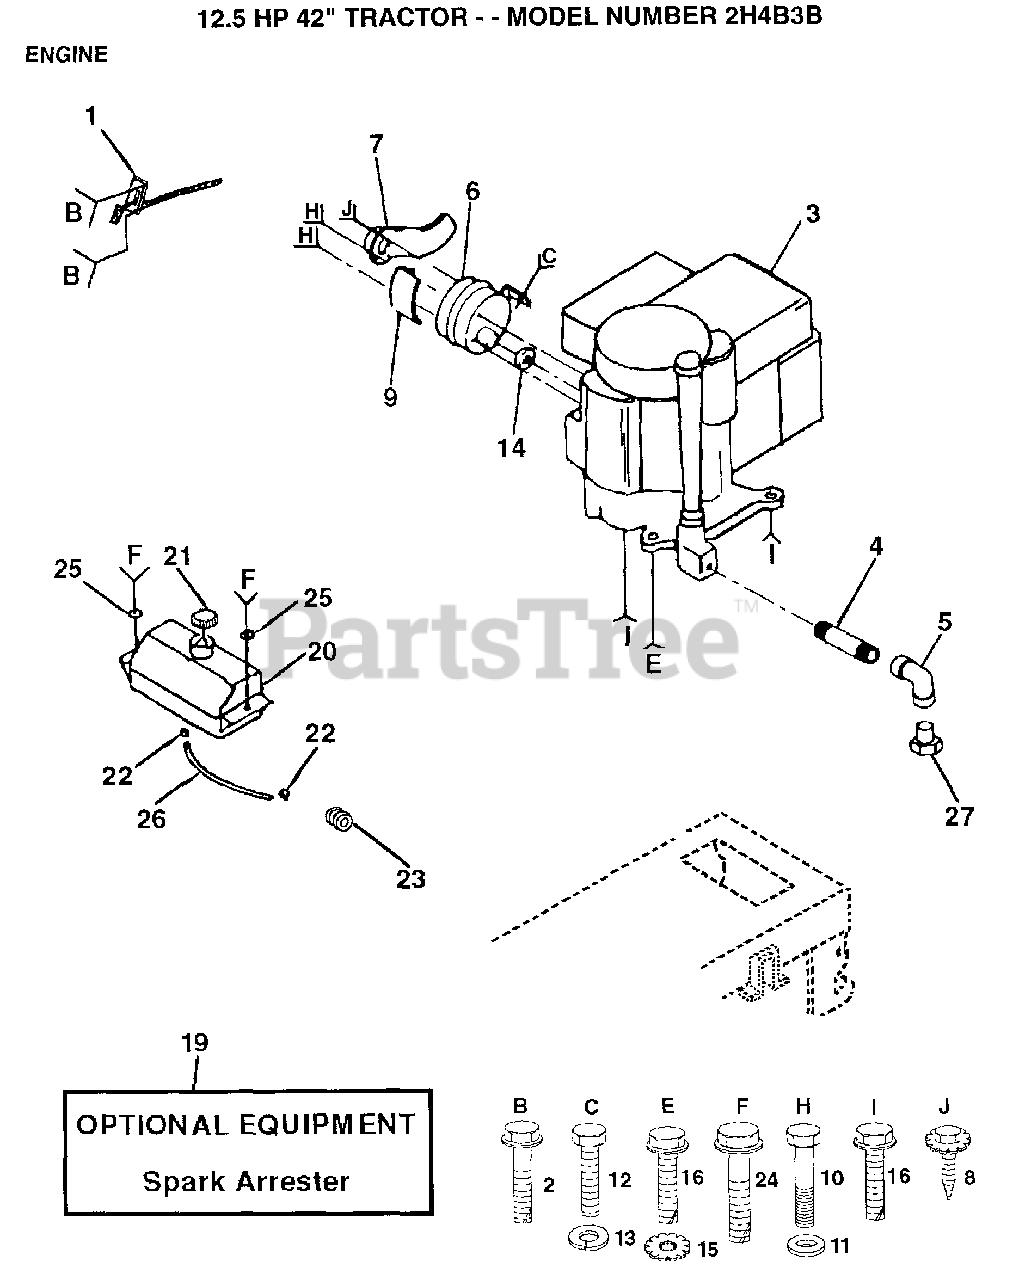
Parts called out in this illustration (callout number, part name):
1	THROTTLE CONTROL
2	SCREW LT
4	PIPE NIPPLE
5	ELBOW
6	MUFFLER LTV
7	DEFLECTOR MUFFLER
9	SHIELD HEAT LTV
10	"BOLT,HEX"
11	WASHER T
12	BOLT
13	LOCKWASHER
15	LOCKWASHER
16	SCREW
20	TANK.FUEL.LT.
21	CAP ASM FUEL
22	HOSE CLAMP
24	SCREW HEX CRT
25	WASHER
26	LINE FUEL
